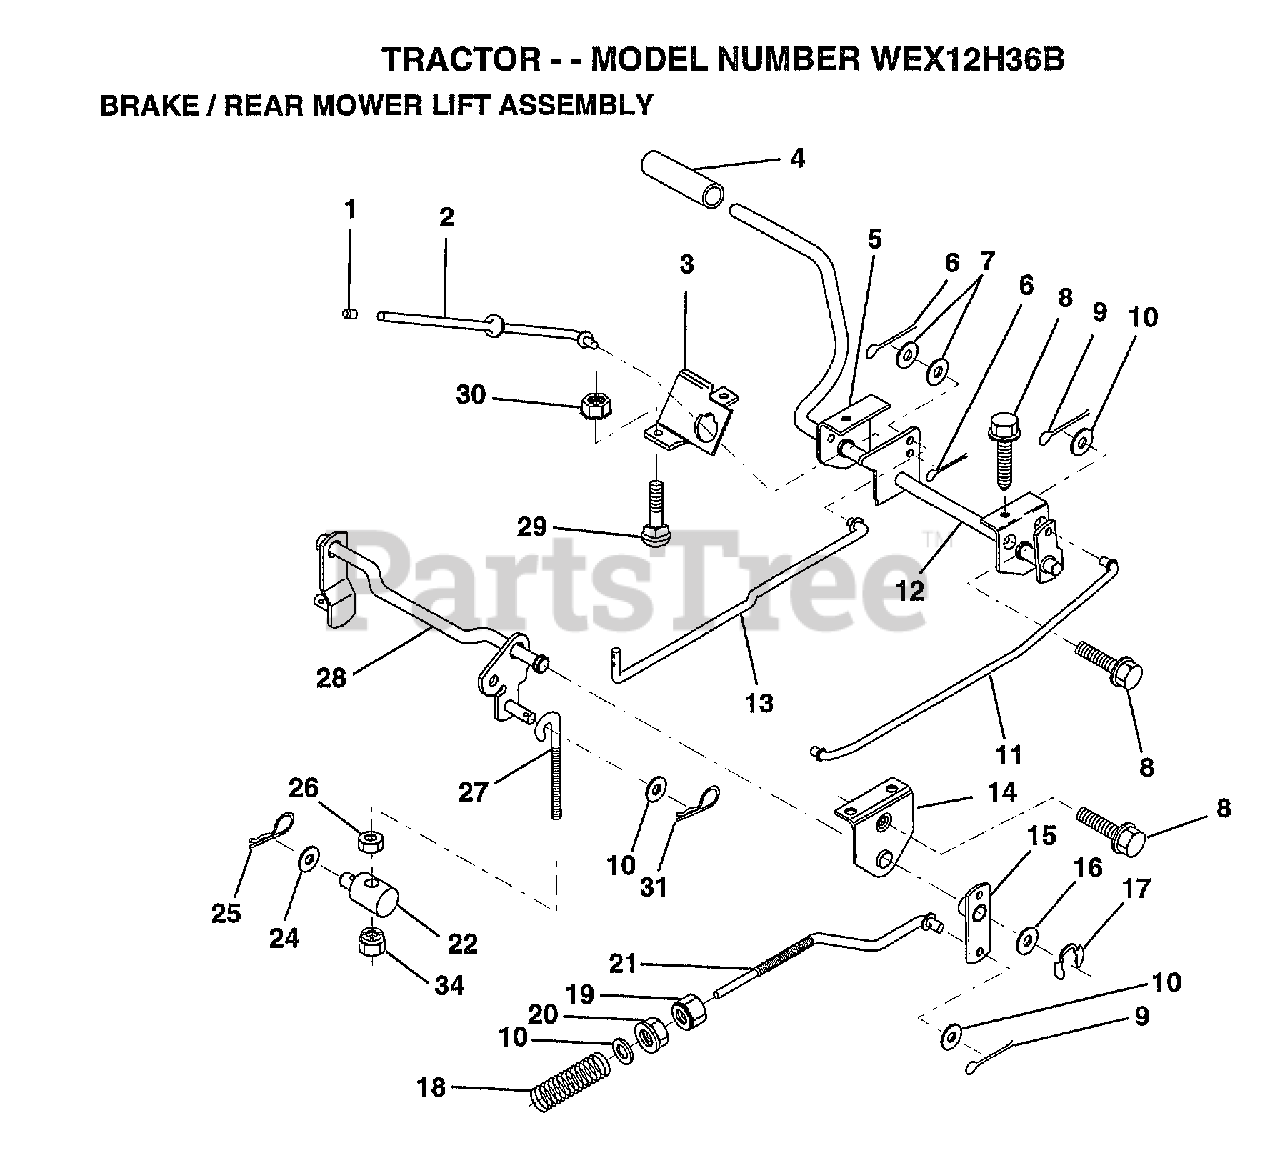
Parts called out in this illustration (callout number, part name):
1	PLUNGER CAP T
2	"ROD,PARK BRAKE"
3	"BRKT,PARK BRAKE"
4	FOOT PEDAL COVER
5	"BRKT,CLU PEDAL LH"
7	WASHER
8	SCREW LT
9	COTTER PIN
10	WASHER
11	"ROD,FRT BRAKE"
12	PEDAL ASM CL/BK36
13	"ROD,CLUTCH"
14	"BRKT,LIFT SHAFT"
15	PVT BRAKE ARM ASM
16	WASHER T
17	KLIP RING
18	SPRING ROD BRAKE
19	NUT
20	NUT
21	ROD.BRAKE.HYDRO
22	TRUNNION.LIFT.
24	WASHER
25	SPRING.RETAINER
26	LOCKNUT
27	LINK, THREADED
28	LIFT ASM MOW REAR
31	RETAINER.SPRING
